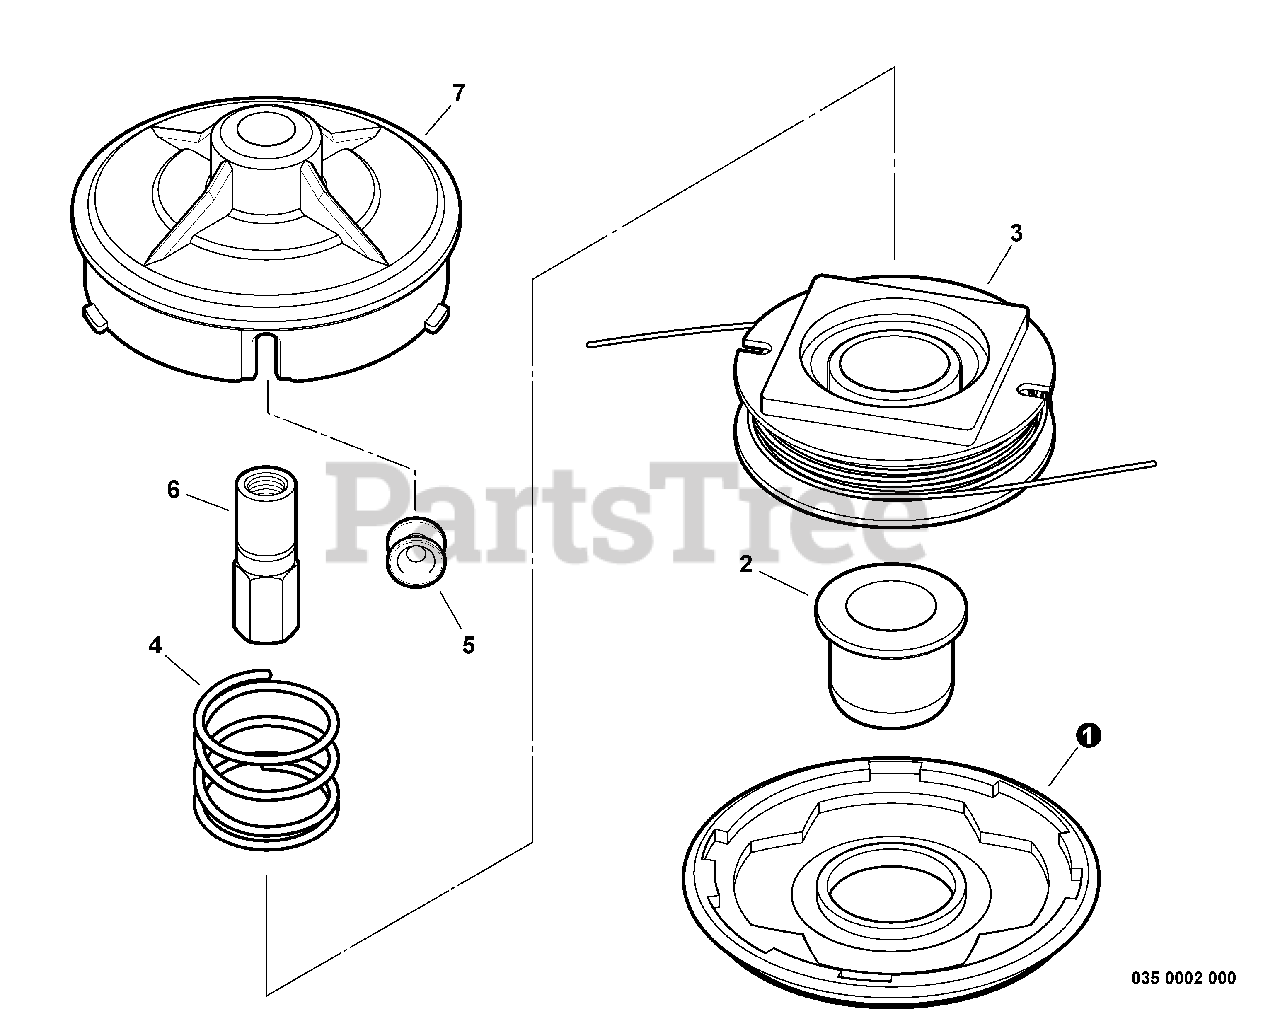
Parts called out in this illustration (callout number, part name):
2	BUTTON
3	SPOOL ASSY
4	SPRING
5	EYELET
